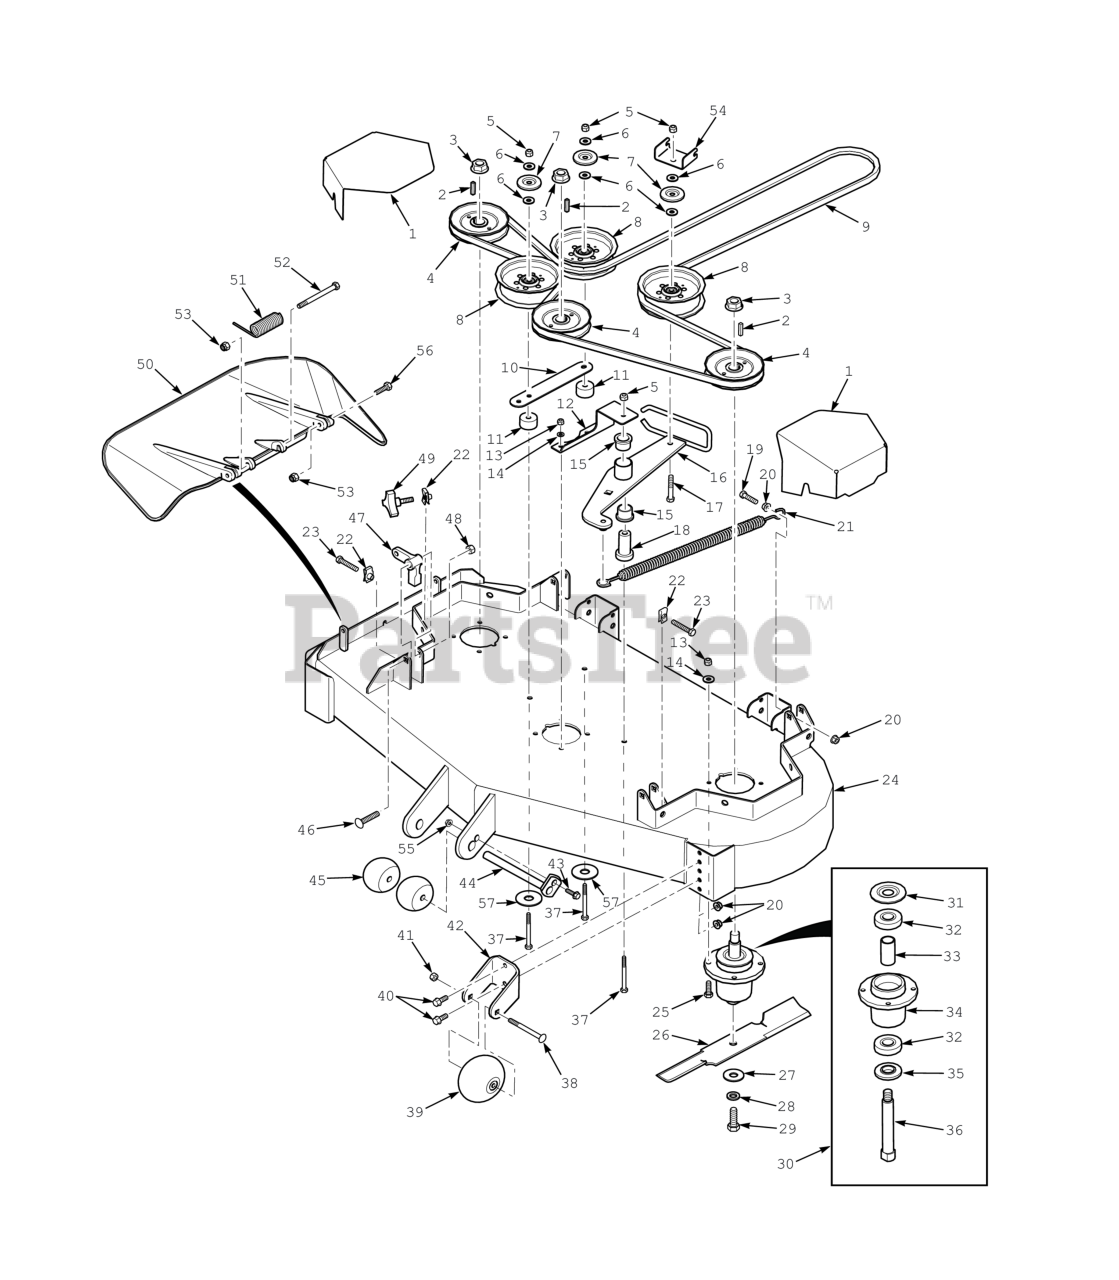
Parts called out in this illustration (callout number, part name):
1	Belt Cover
2	Key, 1/4 x 1/4 x 1.25" Pulley Mtg.
3	Nut, 3/4-16 Spriral Lock
4	Pulley, 5.73" OD - 25mm Bore
5	HEX NUT, ELASTIC STOP LOCK, 3/8-16
6	Flatwasher, 3/8 (.391 x .938 x .105 HD) Grade 8
7	Quick Pin, 5/16" Dia.
8	Pulley, 5" Idler
9	Belt, Cutter Deck
10	Brace, Pulley
11	Spacer, Idler Pulley
12	Support, Idler Pivot - 52
13	Lock Nut, 5/16-18 Elastic Stop Grade 8
14	Lockwasher, 5/16 (.317 x .586 x .078) Helical Spring
15	Bearing, Plastic
16	Idler Arm (incl. item #15)
17	Capscrew, Hex Head 3/8-16 x 2-1/2"
18	Pivot, Idler
19	Bolt, Hex Head 3/8-16 x 1-1/2" Grade 8 Black
20	NUT, 3/8-16 SERRATED FLANGE HEX HEAD
21	Spring, Cutter Deck Idler
22	U-Nut, 3/8-16 (short)
23	Bolt, Hex Head 3/8-16 x 2" Special Lock
24	Cutter Deck w/Decals
25	Bolt, Hex Head 5/16-18 x 1-1/2" (Right Front Engine Mounting, Briggs and Kohler Only)
26	Cutter Blade, 18" (52V)
27	Flatwasher, 5/8-.688 x 1-3/4 x .134 HD
28	Lockwasher, 5/8" Spring
29	Bolt, Hex Head 5/8-11 x 1-1/2"
30	Spindle Assembly
31	Debris Shield
32	Bearing
33	Spacer, Bearing
34	Spindle Housing Assembly
35	Protector, Bearing
36	Shaft, Spindle
37	Bolt, Hex Head, 3/8-16 x 3-1/2"
38	Bolt, Hex Head 3/8-16 x 3-1/2"
39	Bolt, Carriage 3/8-16 x 4"
40	Capscrew, 3/8-16 x 1.0" Serrated Flange Hex Hd
41	Bolt, Hex Head 3/8-16 x 1" Ser. Flg.
42	Bracket, Anti-Scalp, (Black)
43	Bolt, Heax Head 5/16-18 x 1" (48V / 52V)
44	Shaft Weldment, Guide Roller
45	Wheel, Anti-Scalp
46	Bolt, Carriage 7/16-14 x 2-1/4"
47	Bolt, Carriage 7/16-14 x 2-1/4"
48	HEX LOCKNUT, ELASTIC STOP, 7/16-14
49	Knob, w/stud 3/8-16 x 1-1/4"
50	Discharge Chute Assy. SFZ52
51	Spring, Discharge Chute
52	Bolt, 5/16-18 x 4-3/4" Hex Head
53	HEX NUT, ELASTIC STOP LOCK, 5/16-18
54	Bracket, Belt Guide
55	Nut, Serrated Flange 5/16-18 (Right Front Engine Mounting, Briggs and Kohler Only)
56	Bolt, Hex Head 5/16-18 x 1-1/2" - Front
57	Flatwasher, 3/8-.406 x 2.25" x .1875
